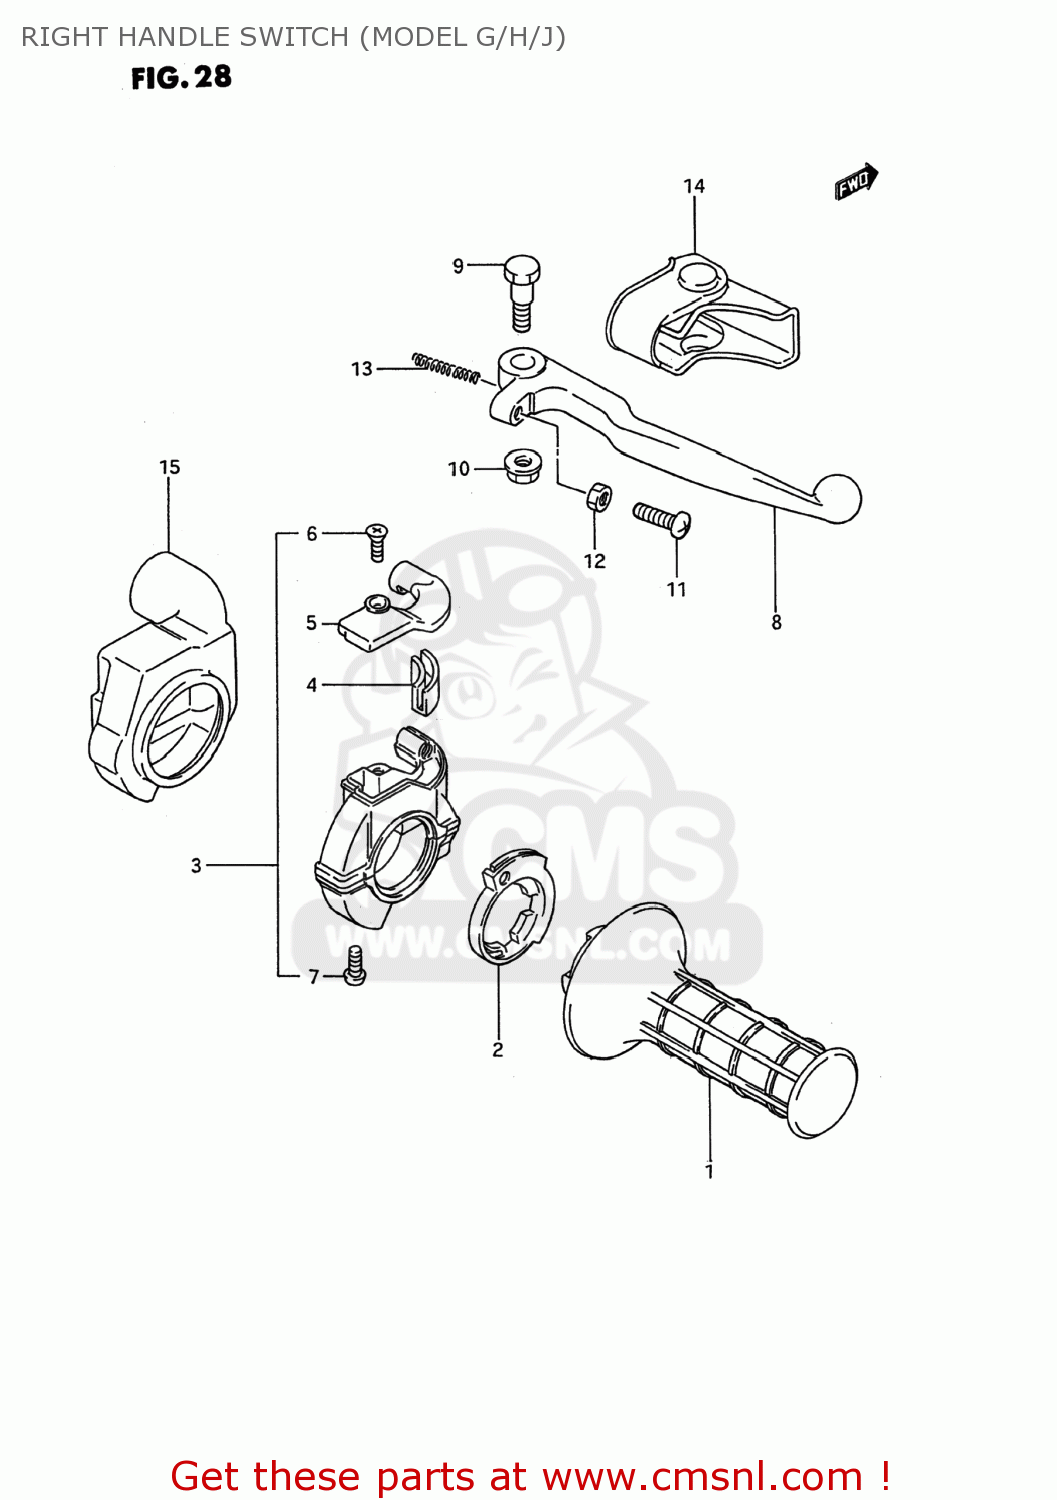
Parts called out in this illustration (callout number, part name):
1	GRIP,THROTTLE
2	ROTOR,THROTTLE GRIP
3	CASE ASSY,THROTTLE
4	GUIDE PIECE,THROTTLE
5	COVER,THROTTLE CASE
6	SCREW 4X10
7	SCREW
8	LEVER,BRAKE
9	BOLT,BRAKE LEVER
10	NUT,BRAKE LEVER
11	BOLT,ADJUST
12	NUT 5MM
13	SPRING,RETURN
14	COVER,BRAKE LEVER
15	COVER,THROTTLE CASE
